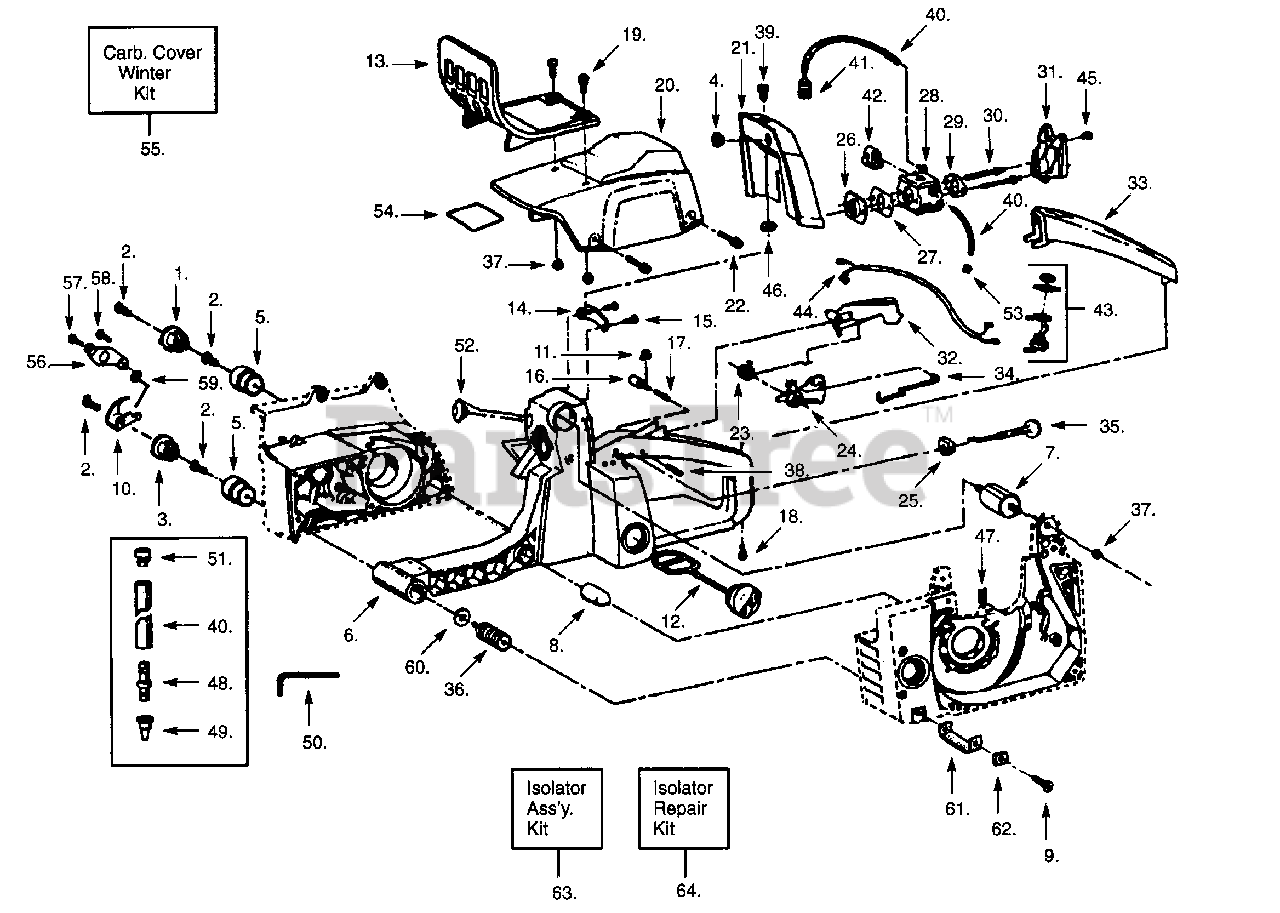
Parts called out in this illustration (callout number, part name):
1	Retainer Mount
3	Chain Catcher Retainer-Serv. Ref. 1
4	Carb. Cover Bumper
5	Lower Isolator
7	Cylindrical Mount
8	Isolator Limiter
9	Type II
10	Chain Catcher-Serv. Ref. 1
11	"C" Clip
12	Fuel Cap Ass'y.
13	Handguard
16	(Two piece design)
16	(One piece design)
17	Throttle Lock Spring
20	Cylinder Shield Kit (Inc.54.)
21	Carb. Cover
22	Screw
23	Trigger Latch Spring
24	Throttle Trigger
27	Gasket Set
28	Carburetor (HDA-49)
29	Air Filter Plate
30	Carb. Mounting Stud
31	Model 285
31	Model 305 & 335
32	Throttle Lockout
33	Rear Handle Cover
34	Throttle Wire
35	Choke Knob
38	Dowel Pin
40	Line Kit (Bulk 530-008133)
41	Fuel Filter Ass'y.
43	Switch Kit
44	Lead Wire Ass'y.
45	Screw
46	Screw Retainer
47	Impulse Fitting
48	Vent Fitting
49	Check Valve
50	Hex Key
51	Vent Plug
52	Air Box Plug
54	Reflector
55	Carb. Cover Winter Kit
56	Bracket Kit-Service Ref. 1
60	Washer-Typell Only
61	AV Strap-Typell Only
62	Strap Retainer Plate-Type II Only
63	Isolator Ass'y. Kit-Type II Only
64	Isolator Repair Kit-Type II Only
